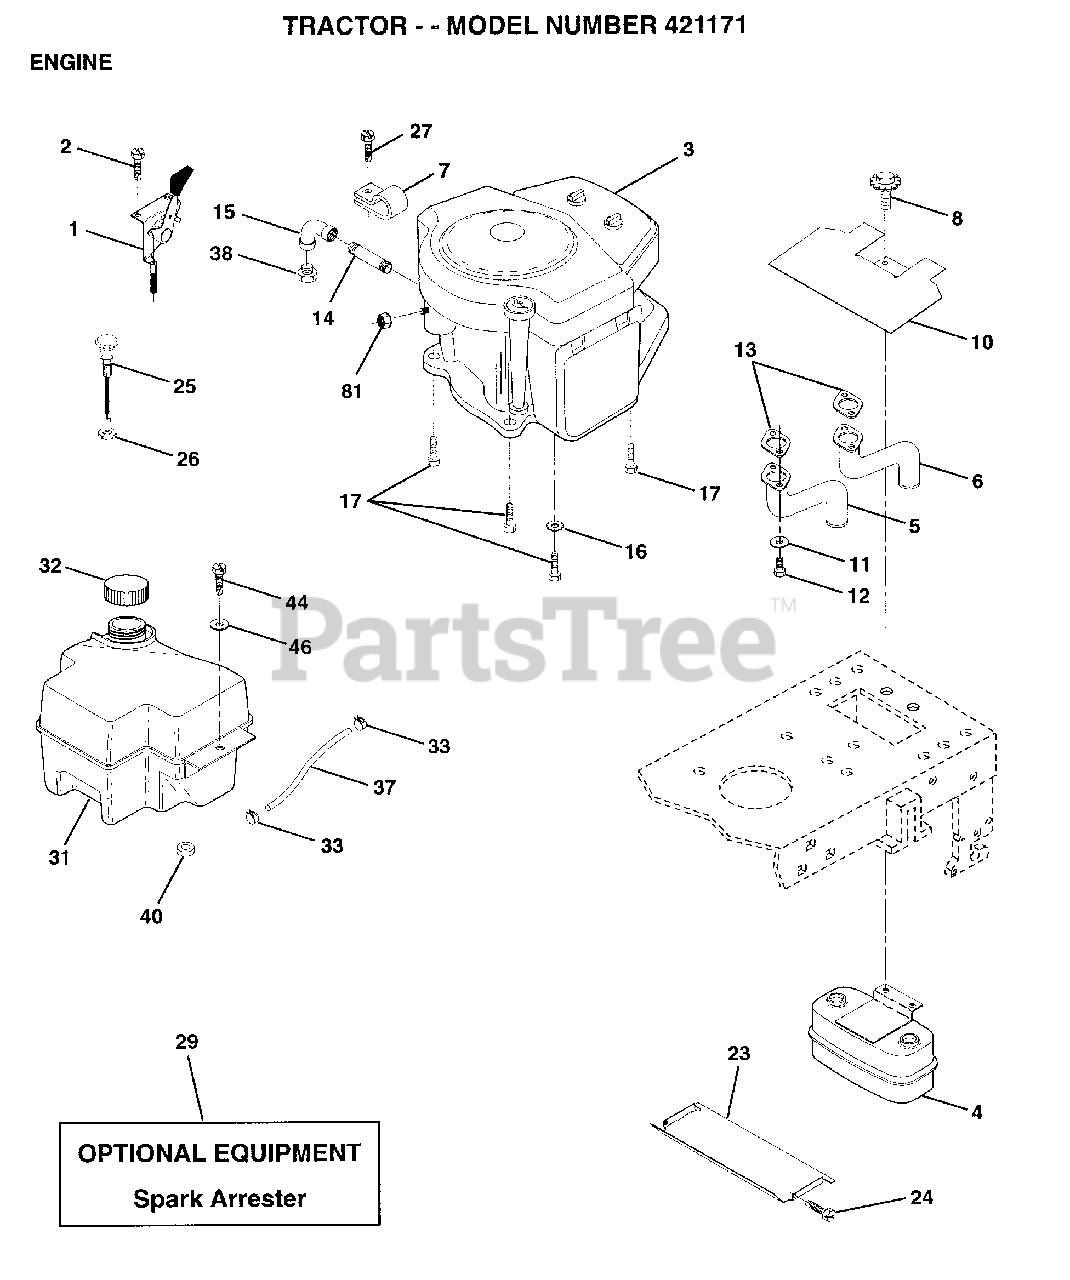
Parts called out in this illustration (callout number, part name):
1	CONTROL THROT LH FLG 35.5
2	SCREW LT
4	MUFFLER.TW.LOTONE
6	EXHAUST.B&S.18.RH
7	CLAMP.TUBE.DBL.EN
8	EXHAUST.B&S.18.LH
8	BOLT.5/16-18.UNC
9	SCREW ST
10	SHIELD.HEAT.
14	PIPE NIPPLE LT
15	ELBOW
16	LOCKWASHER
17	SCREW LT
23	HEAT SHIELD
24	SCREW
25	CONTROL.CHOKE.37
26	"NUT,KEPS 3/8-24IM"
27	SCREW.10-24X1/2
32	CAP ASM FUEL
33	HOSE CLAMP
37	LINE FUEL
44	SCREW HEX CRT
46	WASHER
81	NUT
